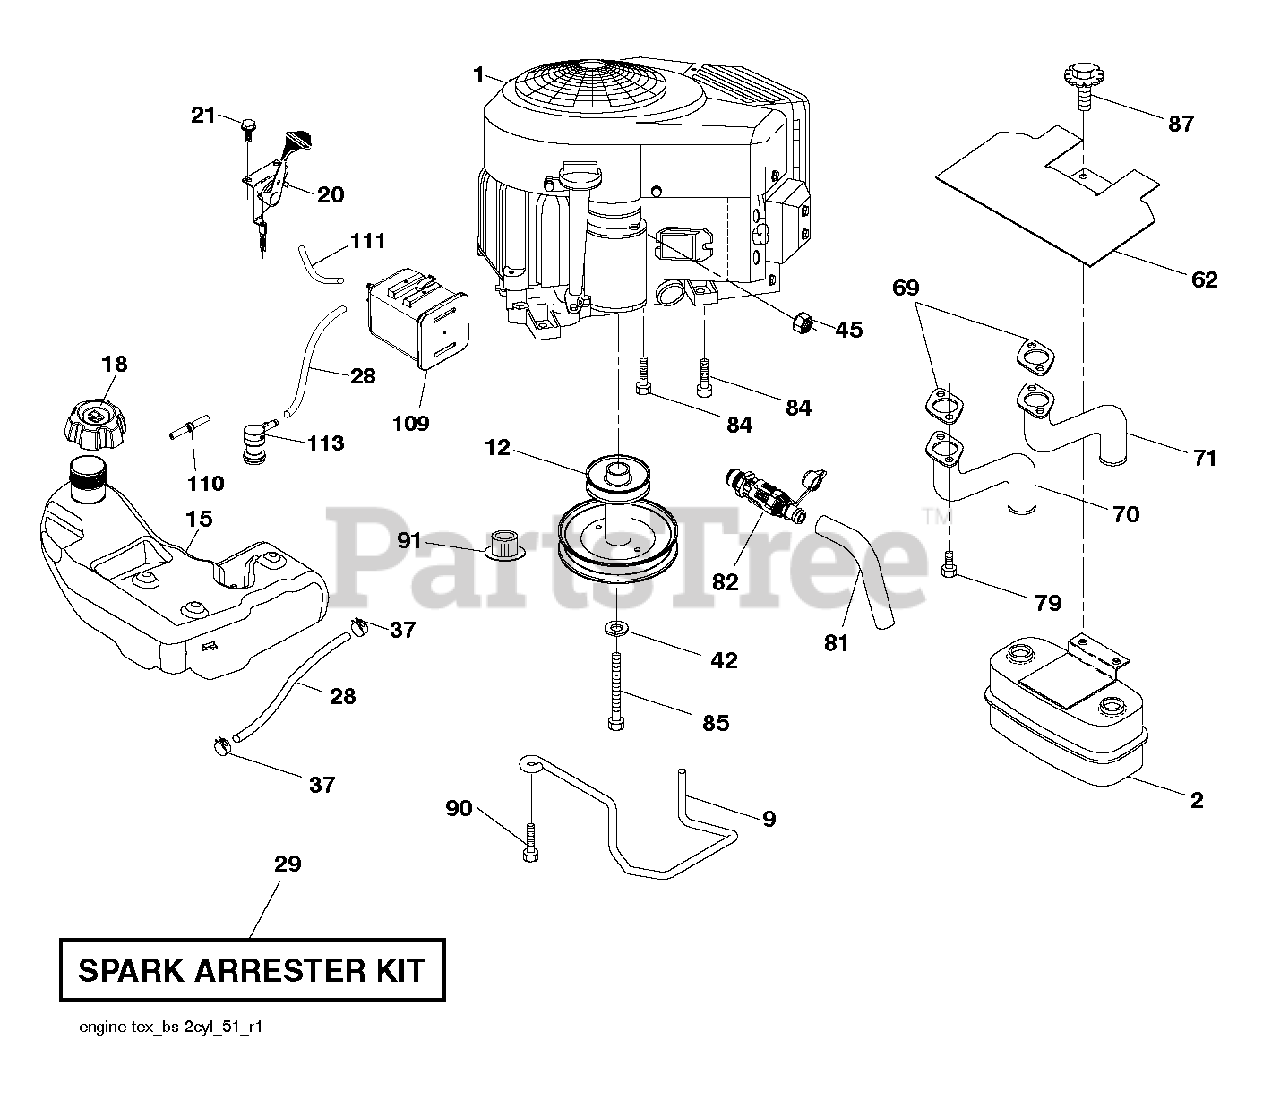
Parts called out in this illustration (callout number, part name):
2	MUFFLER.TWIN.CYL.LOW.TONE
9	KEEPER.BELT.ENGINE.4.2
12	PULLY ENGINE
15	TANK.ASM.FUEL.3GA.CARB
18	CAP ASM.FL.RTCHT.3"GRY.E10
20	CONTROL.TH/CK.COBRA.B&S.TWN.
21	SCREW.#10 X 0.750.BOS (2 2)
28	LINE.FUEL.64"REAR.EMIS
29	KIT.SPARK ARRESTOR(392390 B&S)
37	HOSE CLAMP
42	LOCKWASHER
45	NUT
62	SHIELD.HEAT.MUFFLER
69	GASKET.MUFFLER
70	RP.EXHAUST.TUBE.LH.BS/TWIN
71	RP.EXHAUST.TUBE.RH.BS/TWIN
79	SCREW.SOCKET.HEAD.5/16-18
81	TUBE, DRAIN OIL ASM.
82	VALUE.OIL.DRAIN
84	SCREW.3/8-16
85	BOLT HEX 7/16-20X4-1/4"
87	BOLT, 5/16-18 X 1 3/4
90	SCREW 3/8-16X1
91	BUSHING.1.375OD
109	CANNISTER, CARBON
110	VALVE.ASM.ANTI-SLOSH
111	PURGE.LINE.36"REAR.CALIFORNIA
113	VALVE.SLANT.CARTRDG.90 DEG.TEX
